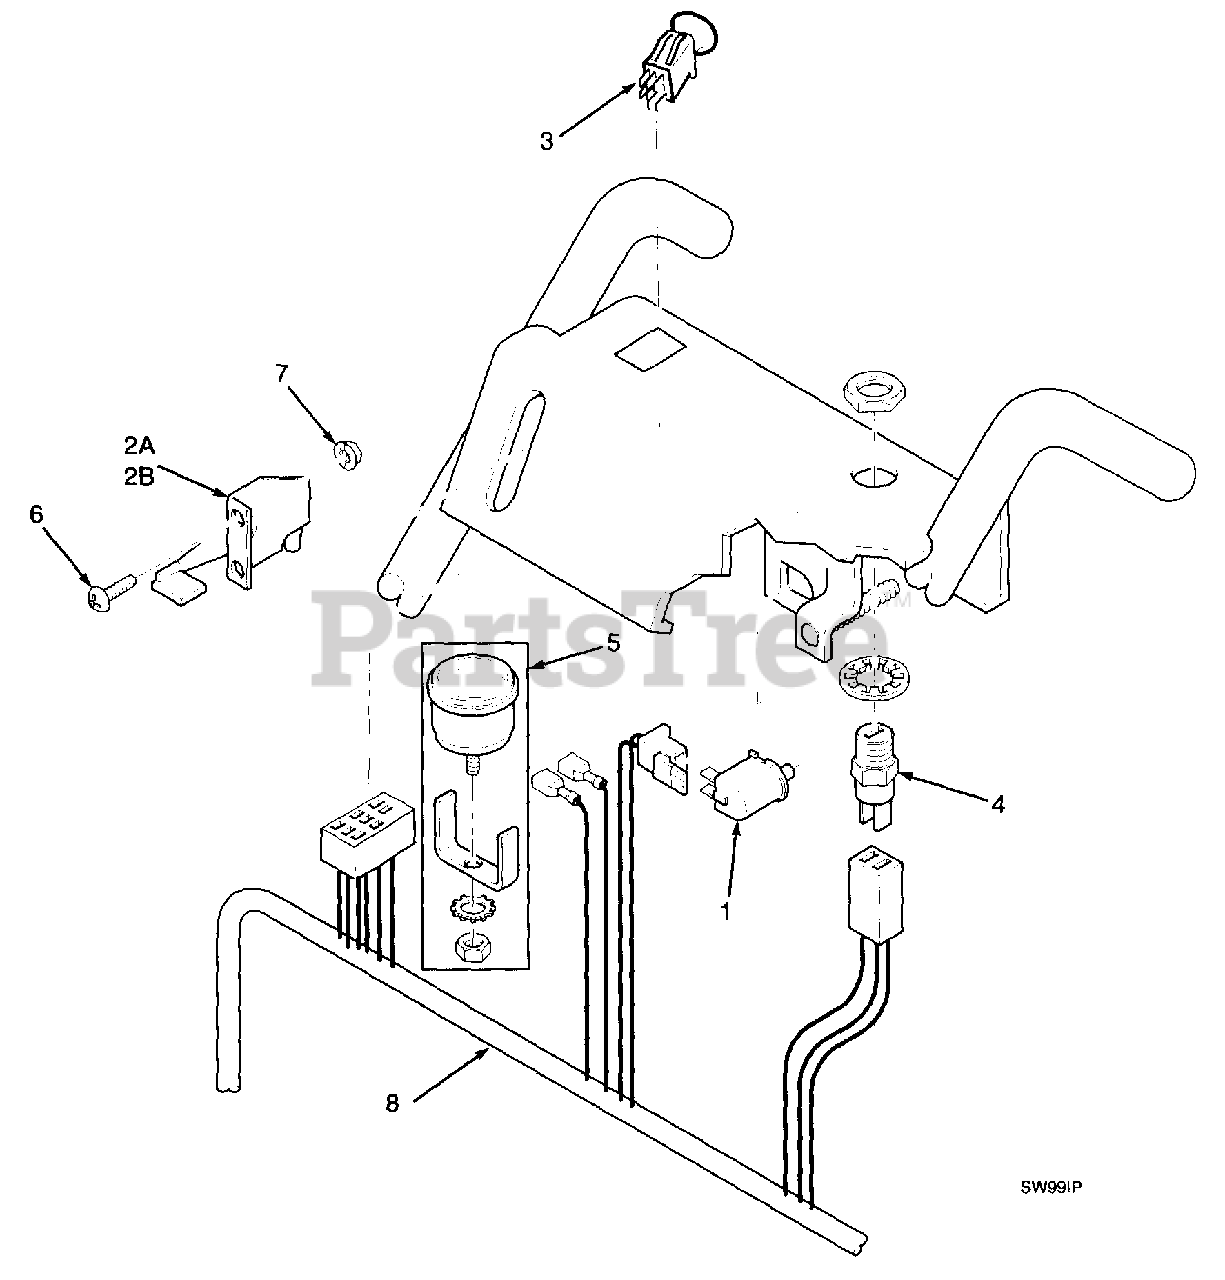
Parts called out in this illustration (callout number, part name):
1	Switch, Neutral Interlock
2B	Throttle Control (17KA)
3	Engagement Switch, Electric Clutch
4	Key Switch
5	Hour Meter
6	Screw, #10-32 x .50 Phillips Washer Head
7	Nut, #10-32 Serrated Flange Hex Head
8	Handle Wire Harness, Manual Start
